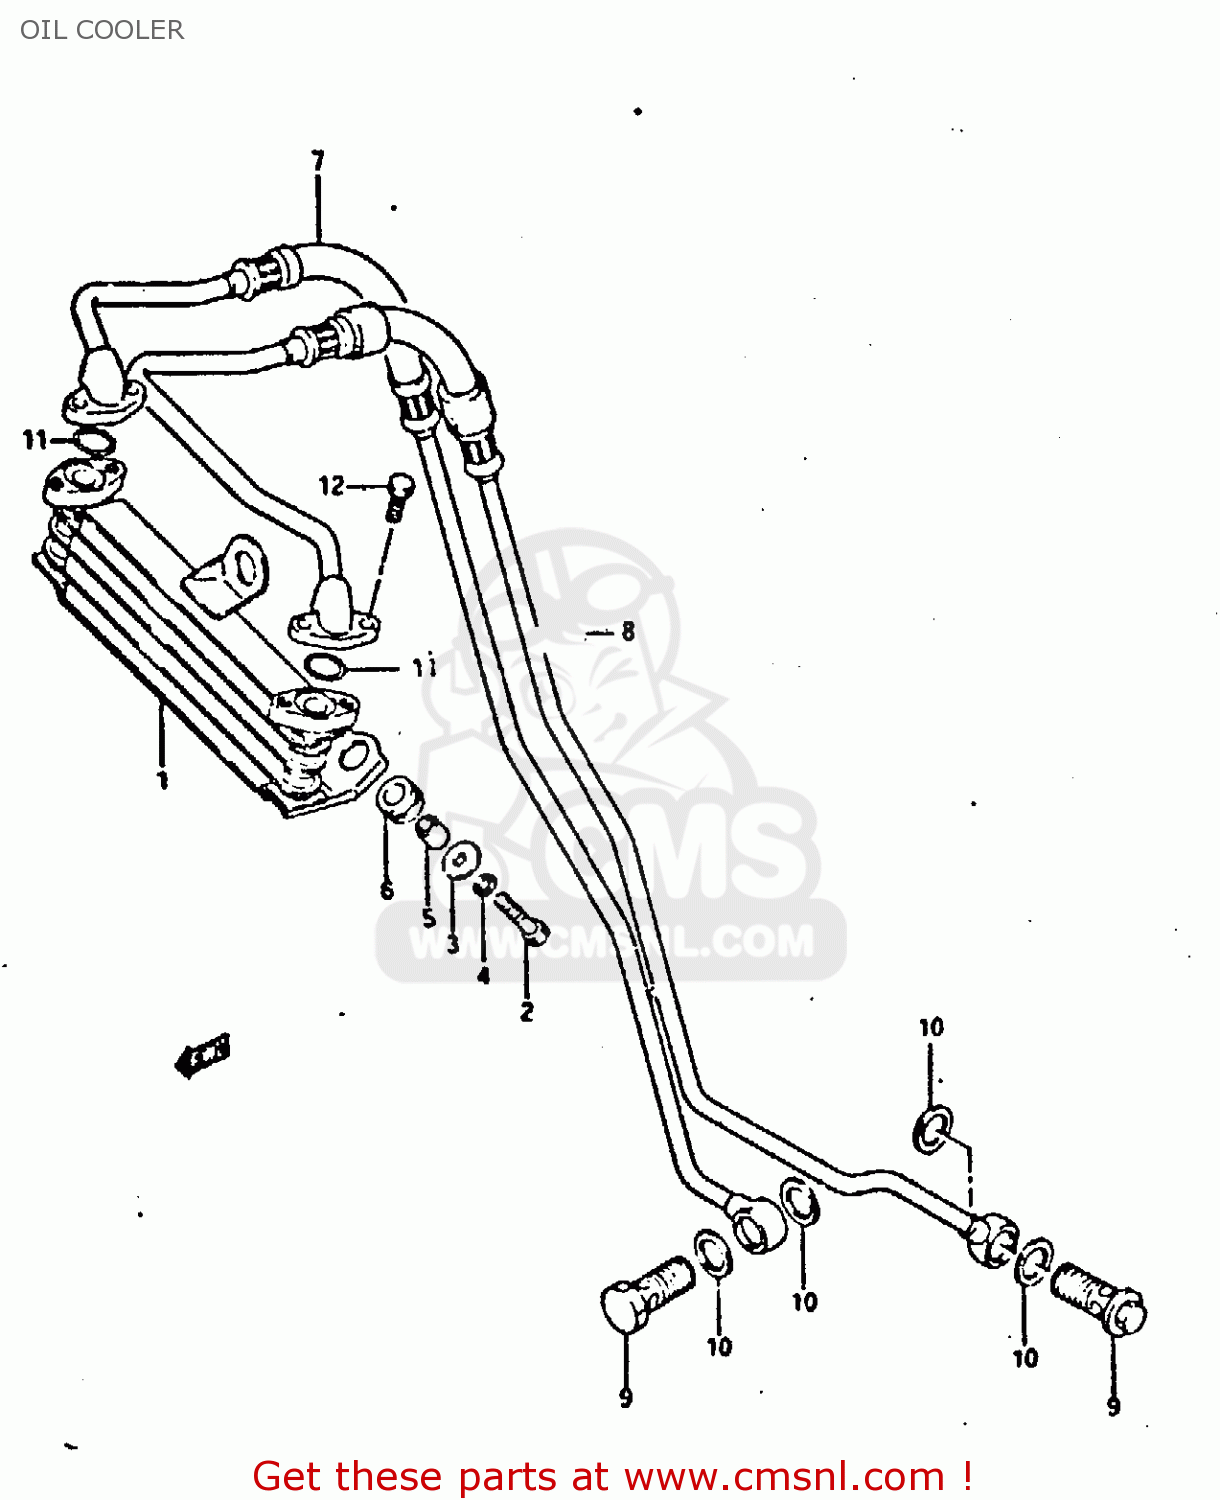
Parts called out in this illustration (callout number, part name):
2	BOLT
3	WASHER
4	WASHER,LOCK
5	SPACER (6.8X10X10)
6	CUSHION
9	BOLT UNION
10	GASKET(14X20X1.5) (NAS)
11	O RING(D:2.4,ID:12.3)
12	BOLT
